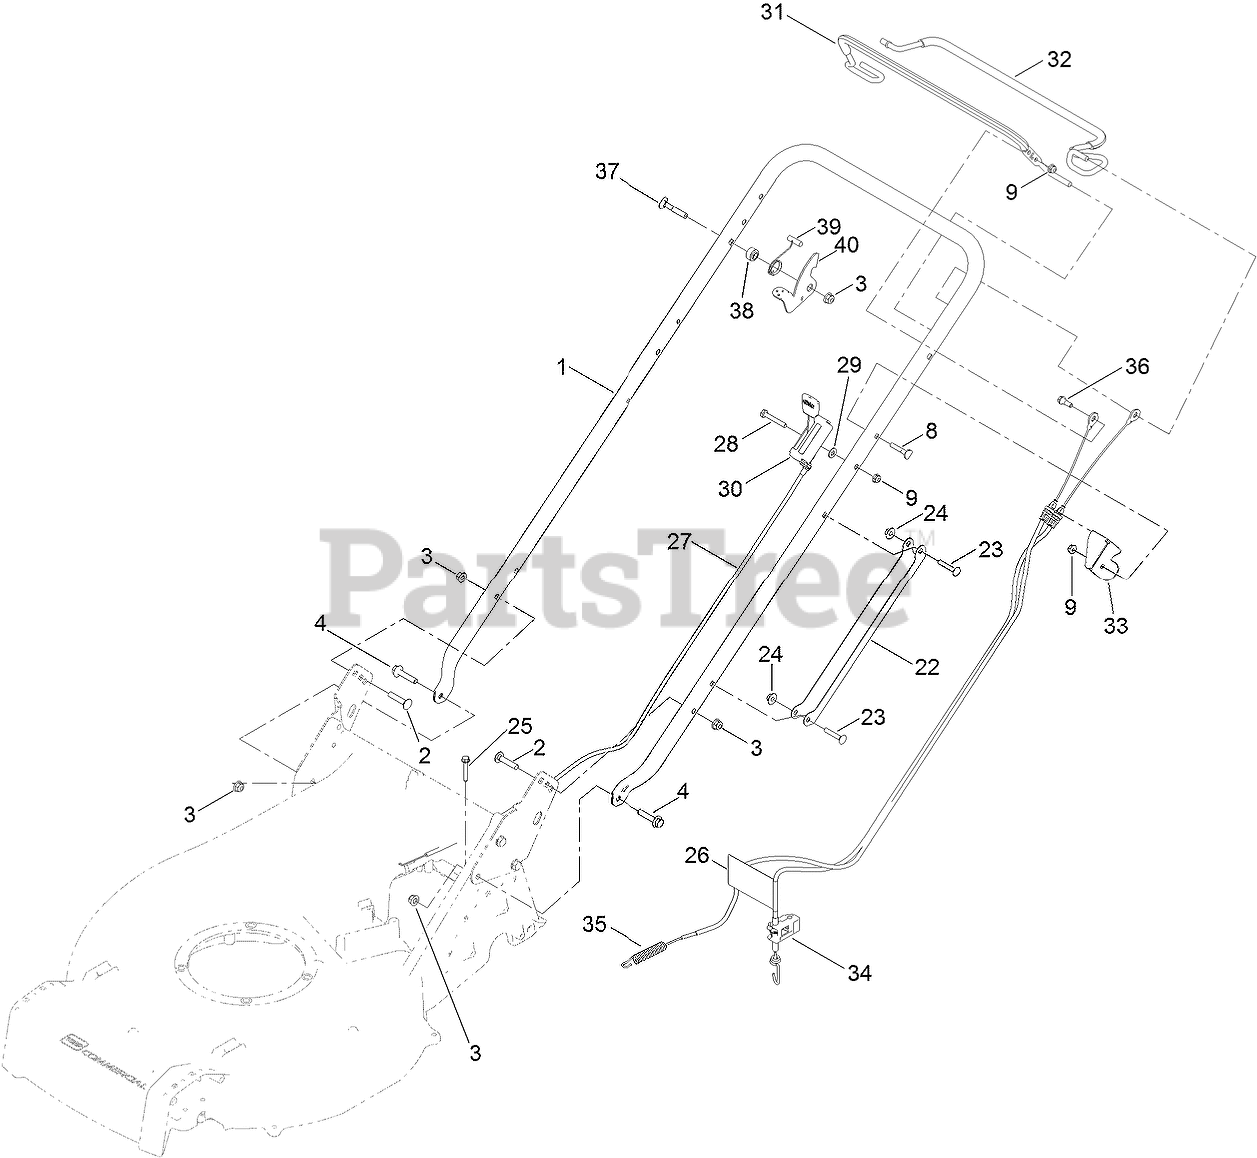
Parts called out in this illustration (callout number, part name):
2	BOLT-CARR
3	NUT-HF, NI
4	SCREW-HHF
8	SCREW-HANDLE
9	NUT-HF
22	GUARD-CABLE, HANDLE
23	SCREW-CARR
24	NUT-HF
25	SCREW-HWH
27	CONTROL-THROTTLE/CHOKE
28	SCREW-HH
29	WASHER-FLAT
30	DECAL-THROTTLE, CHOKE
31	BAIL-BBC, COATED
32	BAIL-TRACTION, COATED
33	BRACKET-CABLE
34	CABLE-TRACTION
35	CABLE-BBC
36	BOLT-SHOULDER
38	BUSHING-STEPPED
39	SPRING-LEVER, BBC
40	LEVER-BBC
